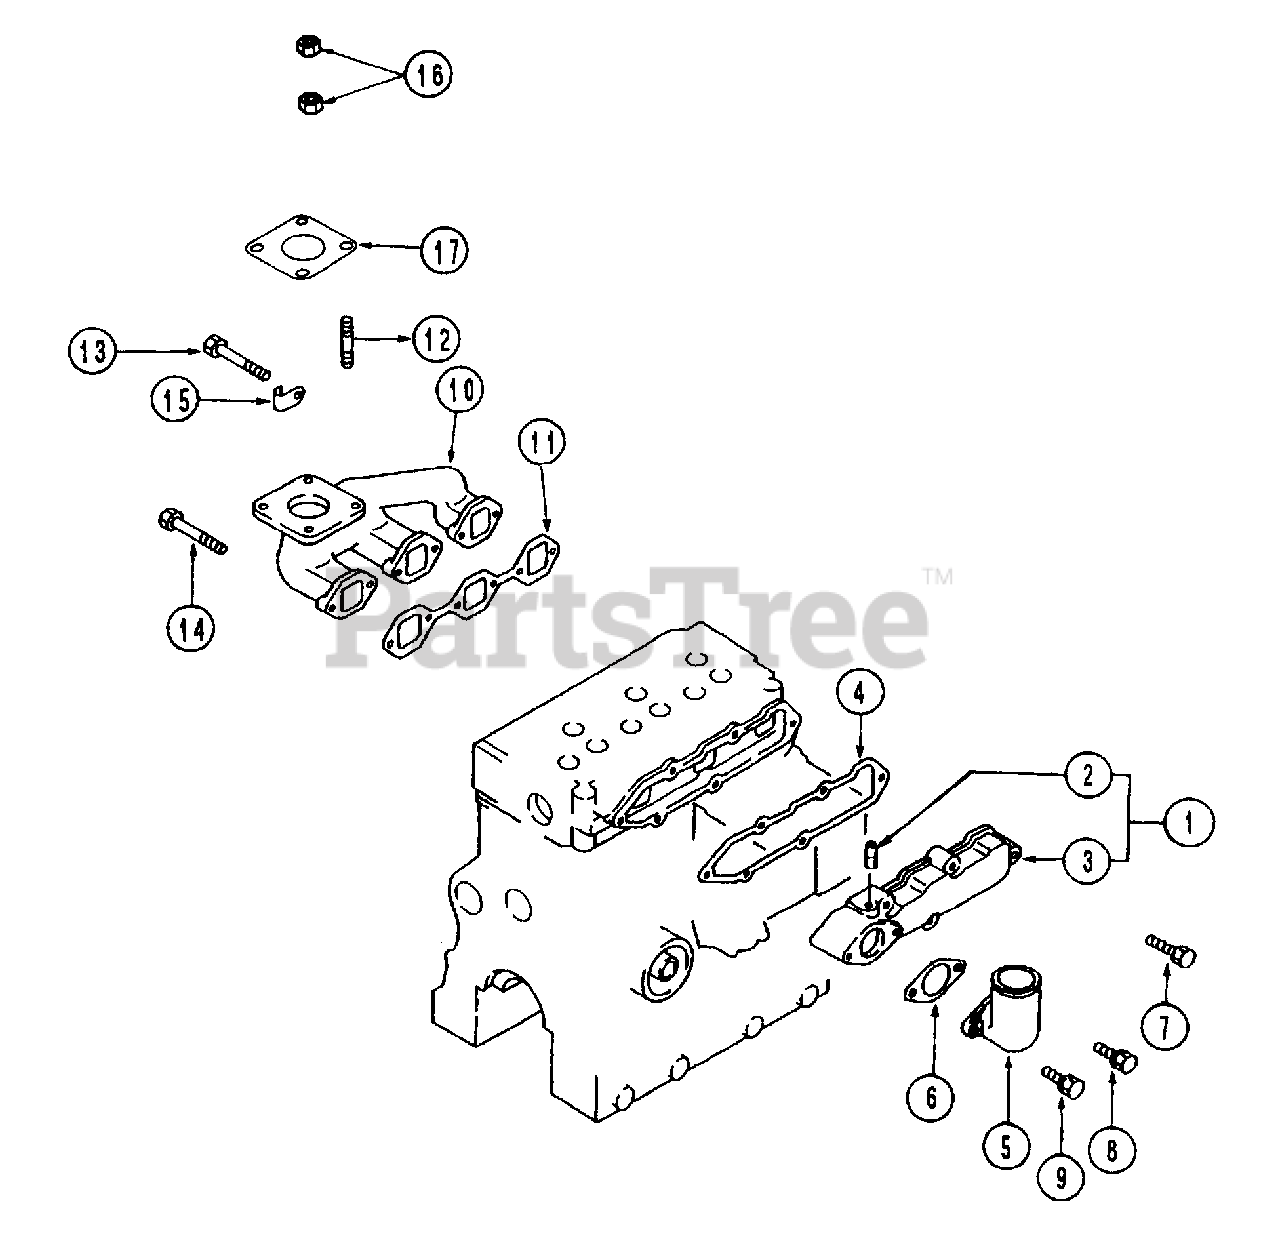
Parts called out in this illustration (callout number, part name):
1	Cover Ass'y, Inlet
2	Pipe
3	Cover, Inlet
4	Gasket, Inlet
6	Gasket, Inlet
7	Bolt, W/Washer
8	Bolt, W/Washer
9	Bolt, W/Washer
10	Manifold, Exh.
12	Stud
